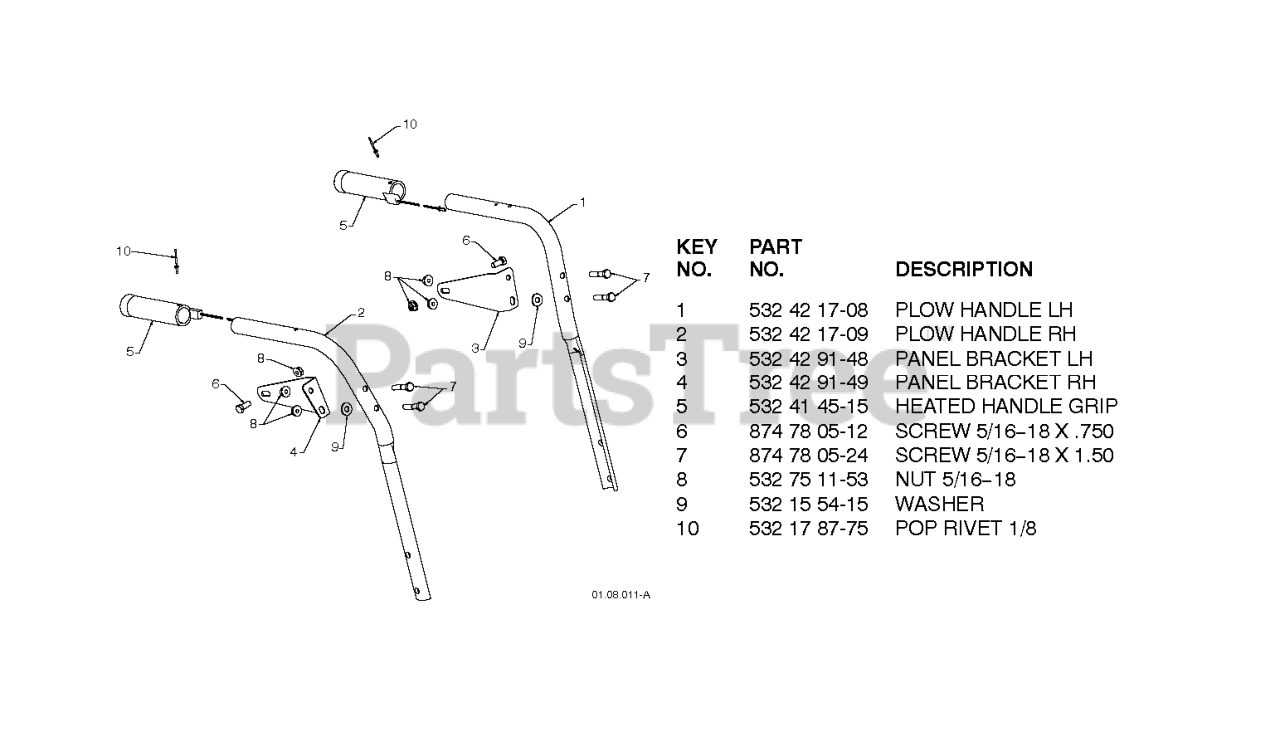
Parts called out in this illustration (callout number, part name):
1	TUBE.HANDLE.PLOW.LH.GREY
2	TUBE.HANDLE.PLOW.RH.GREY
3	BRACKET.PANEL.LH.
4	BRACKET.PANEL.RH.
5	GRIP.HANDLE.HEATED
6	BOLT.FIN.HEX.5/16-18X3/4
7	HEX BOLT
8	NUT.LOCK.5/16-18
9	WASHER.20X8.5
10	RIVET.POP.1/8X
